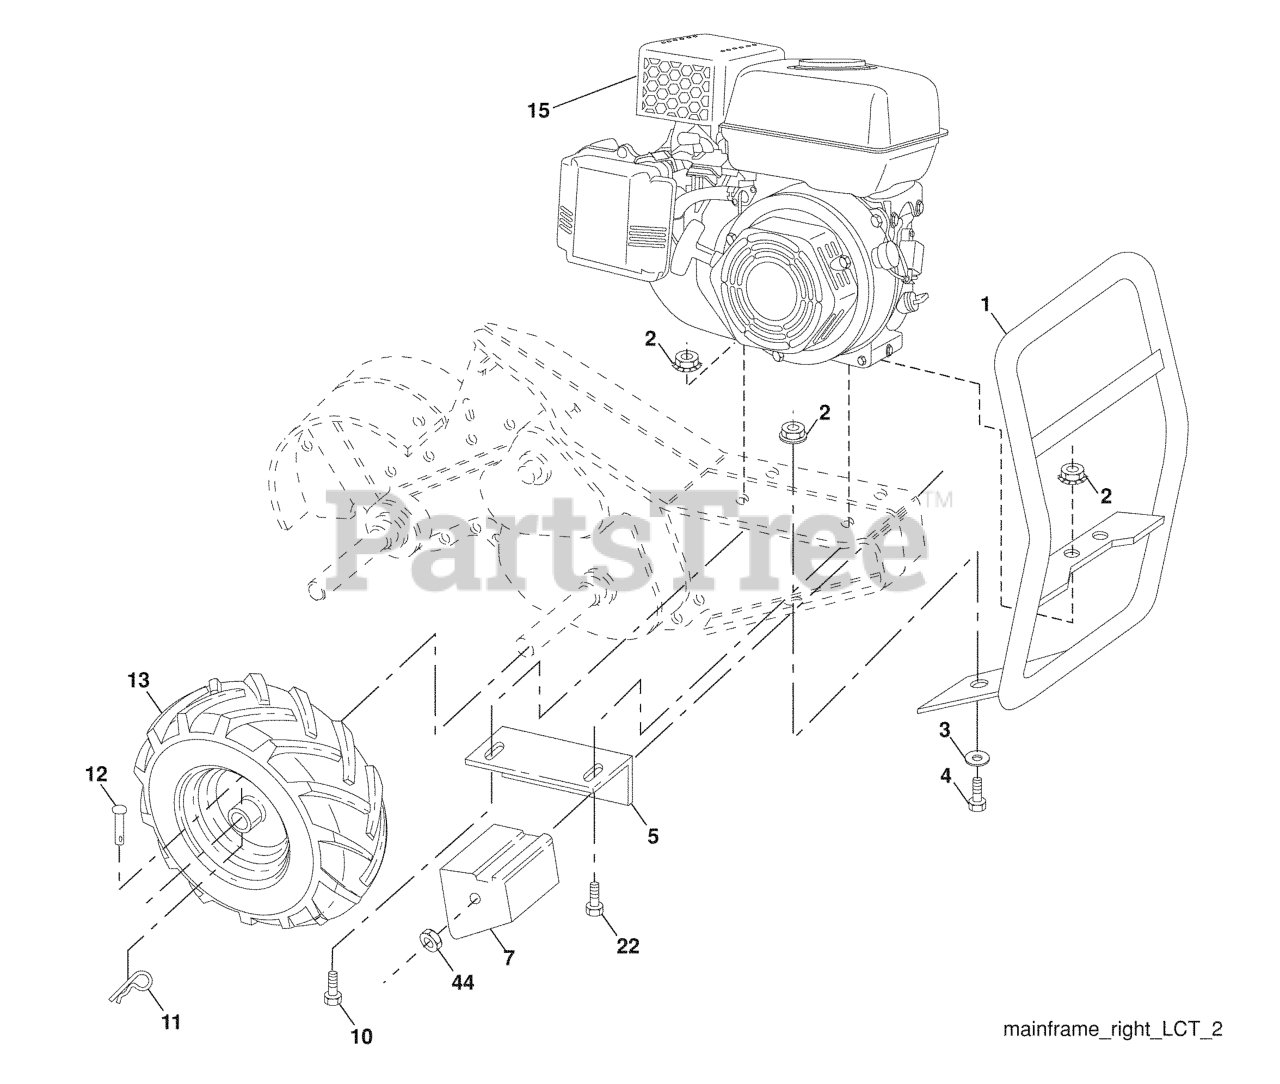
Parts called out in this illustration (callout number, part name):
1	RP.BUMPER.ASM.TILLER.
2	LOCKNUT-FLANGE 5/16-18
3	WASHER
4	BOLT
5	DNO BRACKET RH CRT
7	COUNTERWEIGHT, RH
10	BOLT
11	RETAINER M
12	RIVET,DRILLED
13	TIRE.13X5-6.CHEVRON.TILLER
22	BOLT, HEX 5/16-18X1-3/4
